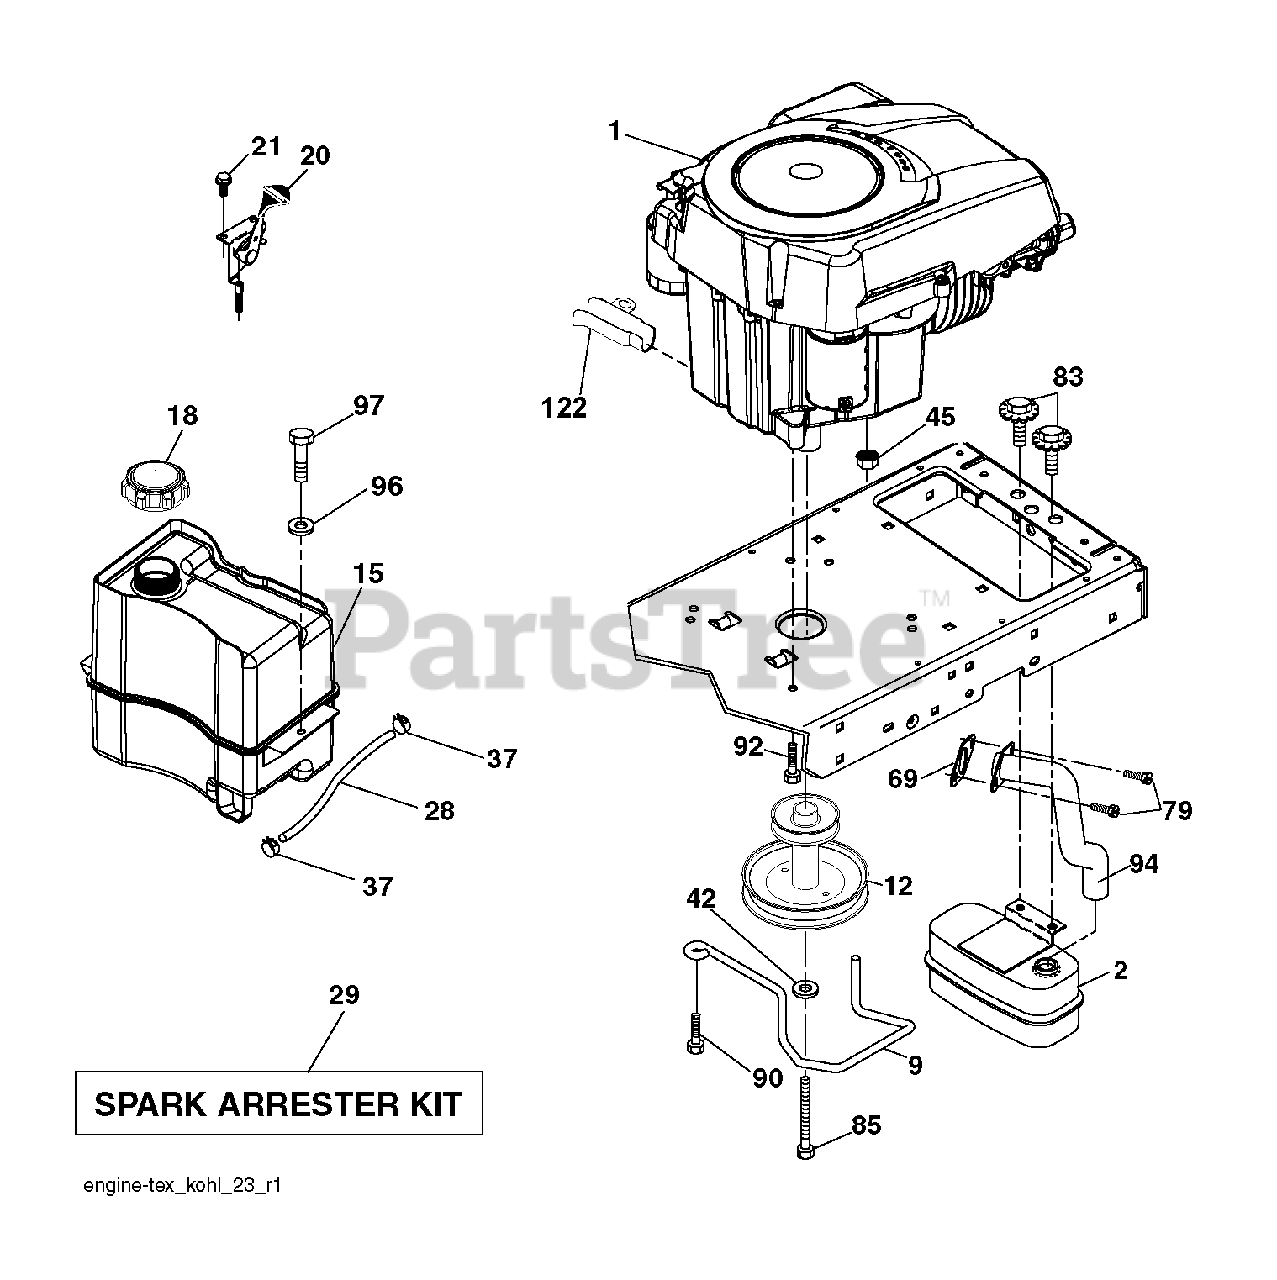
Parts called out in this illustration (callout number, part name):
1	Husqvarna TBD
2	MUFFLER.SINGLE.CYL.KOHL/B&S
9	KEEPER.BELT.ENGINE.3.25 (3 2)
12	PULLEY ENGINE
15	RP TANK FUEL FRT 1.5 GAL
18	CAP ASM.FUEL.2.25"FR.
20	CONTROL.TH/CK.C.
21	SCREW.#10 X 0.750.BOS
28	LINE.FUEL.20
29	KIT.SPARK ARRESTOR 794945 B&S
37	HOSE CLAMP
42	LOCKWASHER
45	NUT
69	GASKET.EXHAUST.KOHLER
79	SCREW.SOCKET HD.5/16-1
83	BOLT, 5/16-18 X 1 3/4
85	BOLT HEX 7/16-20X4-1/4"
90	SCREW 3/8-16X1
92	SCREW 3/8-16X1
94	RP.TUBE.EXHAUST.KOHL.COURAGE
97	SCREW HEXWSHR 1/4-20X3/4
122	EXTENSION DRAIN OIL
